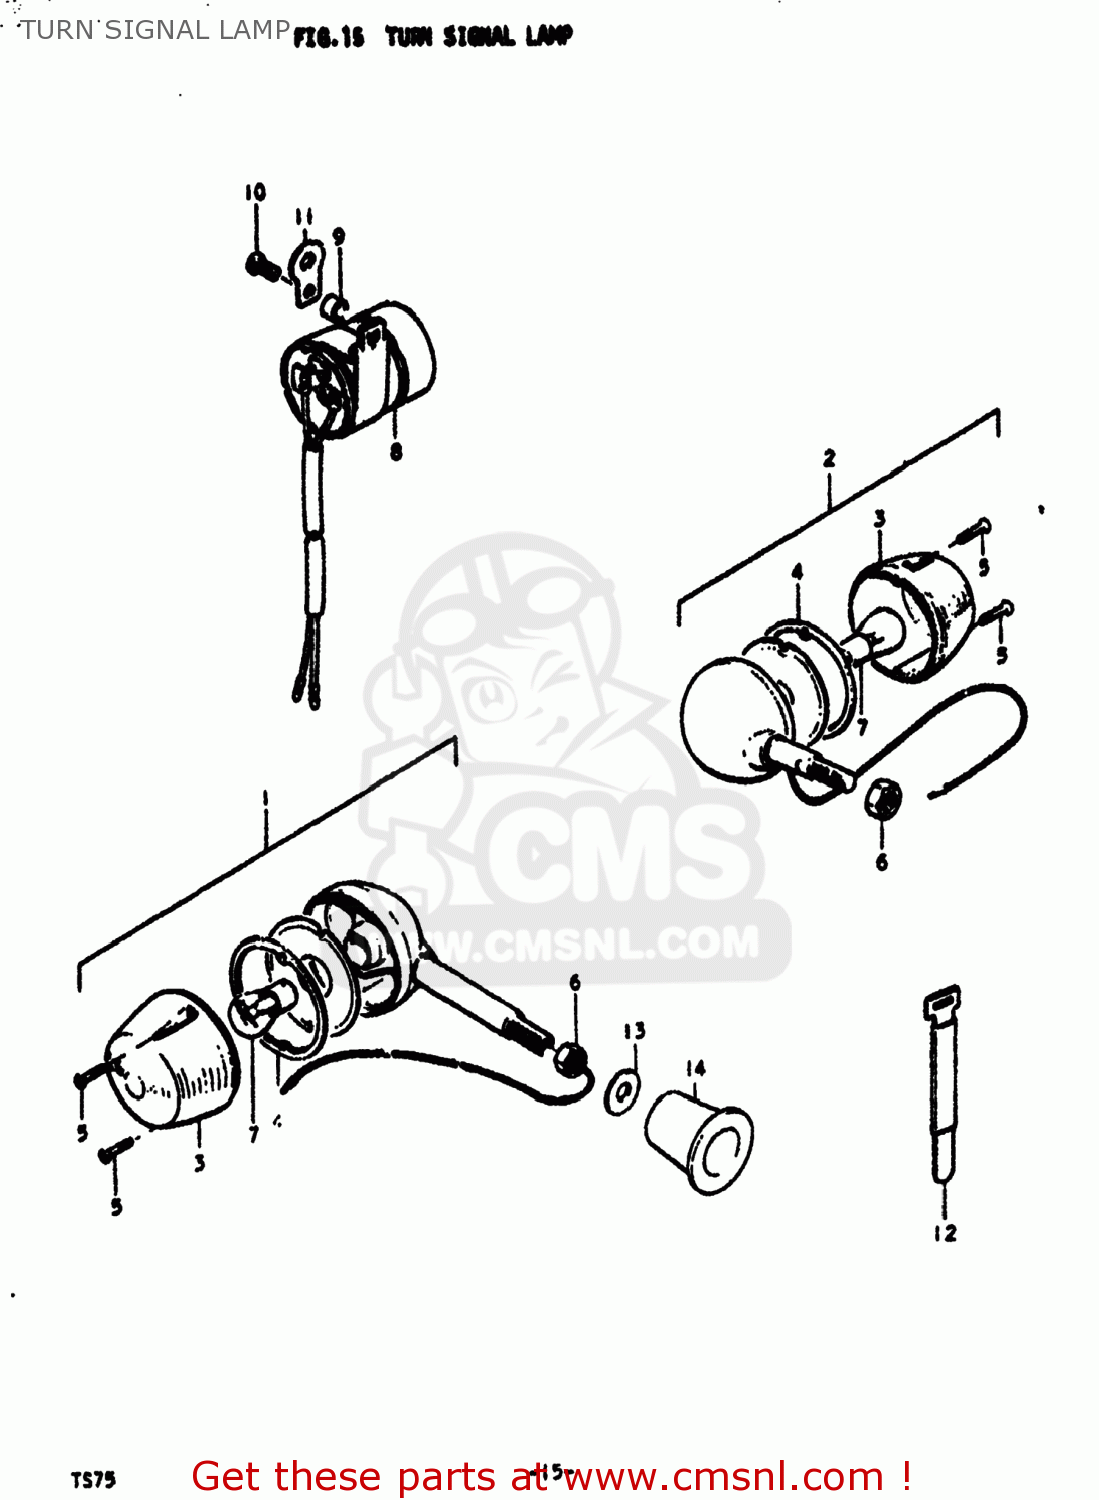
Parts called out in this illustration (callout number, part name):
1	LAMP ASSEMBLY,FRONT TURN SIGNAL
2	LAMP ASSEMBLY,REAR TURN SIGNAL
3	LENS
4	GASKET (NAS)
5	SCREW
6	GASKET (NAS)
7	NUT
8	BULB(6V17W,STANLEY,A4513A)
